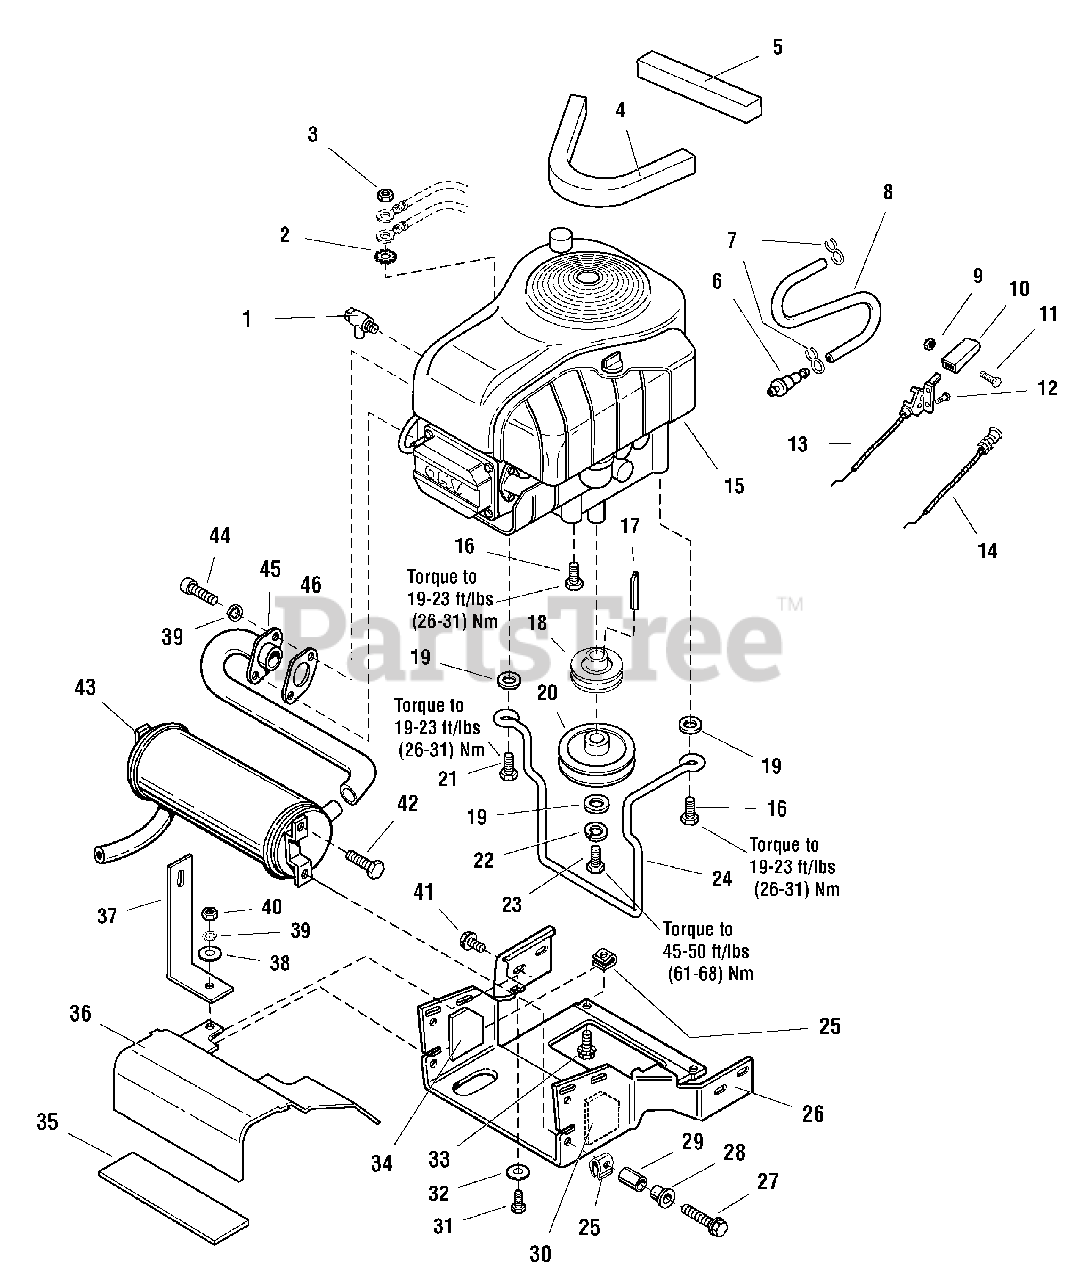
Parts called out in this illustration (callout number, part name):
1	VALVE-SHUT OFF
2	LOCKWASHER, External Tooth 3/8
3	NUT, Hex 3/8-16
6	FILTER, Fuel
7	CLAMP, Hose Type E
8	HOSE, 12" Long
9	NUT, Nylon
11	SCREW, #10-24
12	CAPSCREW, Hex Washer Head 1/4-14 x 5/8
13	CABLE, Throttle Control, 14" Long
14	CHOKE, Control, Push/Pull
15	ENGINE-18HP Briggs & Stratton INTEK SINGLE
16	CAPSCREW, Hex Washer Head, Taptite, 3/8-16 x 1-1/2
17	KEY, Hydro Only
18	PULLEY
19	WASHER
20	PULLEY, 5.40 O.D.
21	CAPSCREW, Hex Washer Head, Taptite, 3/8-16 x 2
22	LOCKWASHER, 7/16
23	CAPSCREW, 7/16-20 x 2
25	NUT, Speed 5/16-18
26	DUCT, Muffler
27	CAPSCREW, Hex Flange Lock, 5/16-18 x 1-1/4
30	INSULATION, LH
31	CAPSCREW, 5/16-18 X 1
32	WASHER
33	CAPSCREW, Hex Flange Lock, 5/16-18 x 3/4
34	INSULATION, RH
36	DUCT, Muffler, Upper
37	STRAP, Torque
39	LOCKWASHER, 5/16
40	NUT, Hex 5/16-18
41	CAPSCREW, Hex Washer Head, Taptite, 5/16-18 x 1/2
42	CAPSCREW, Hex Washer Head, Taptite, 1/4-20 x 3/8
44	CAPSCREW, 5/16-18 x 3/4, G8
45	PIPE, Exhaust
